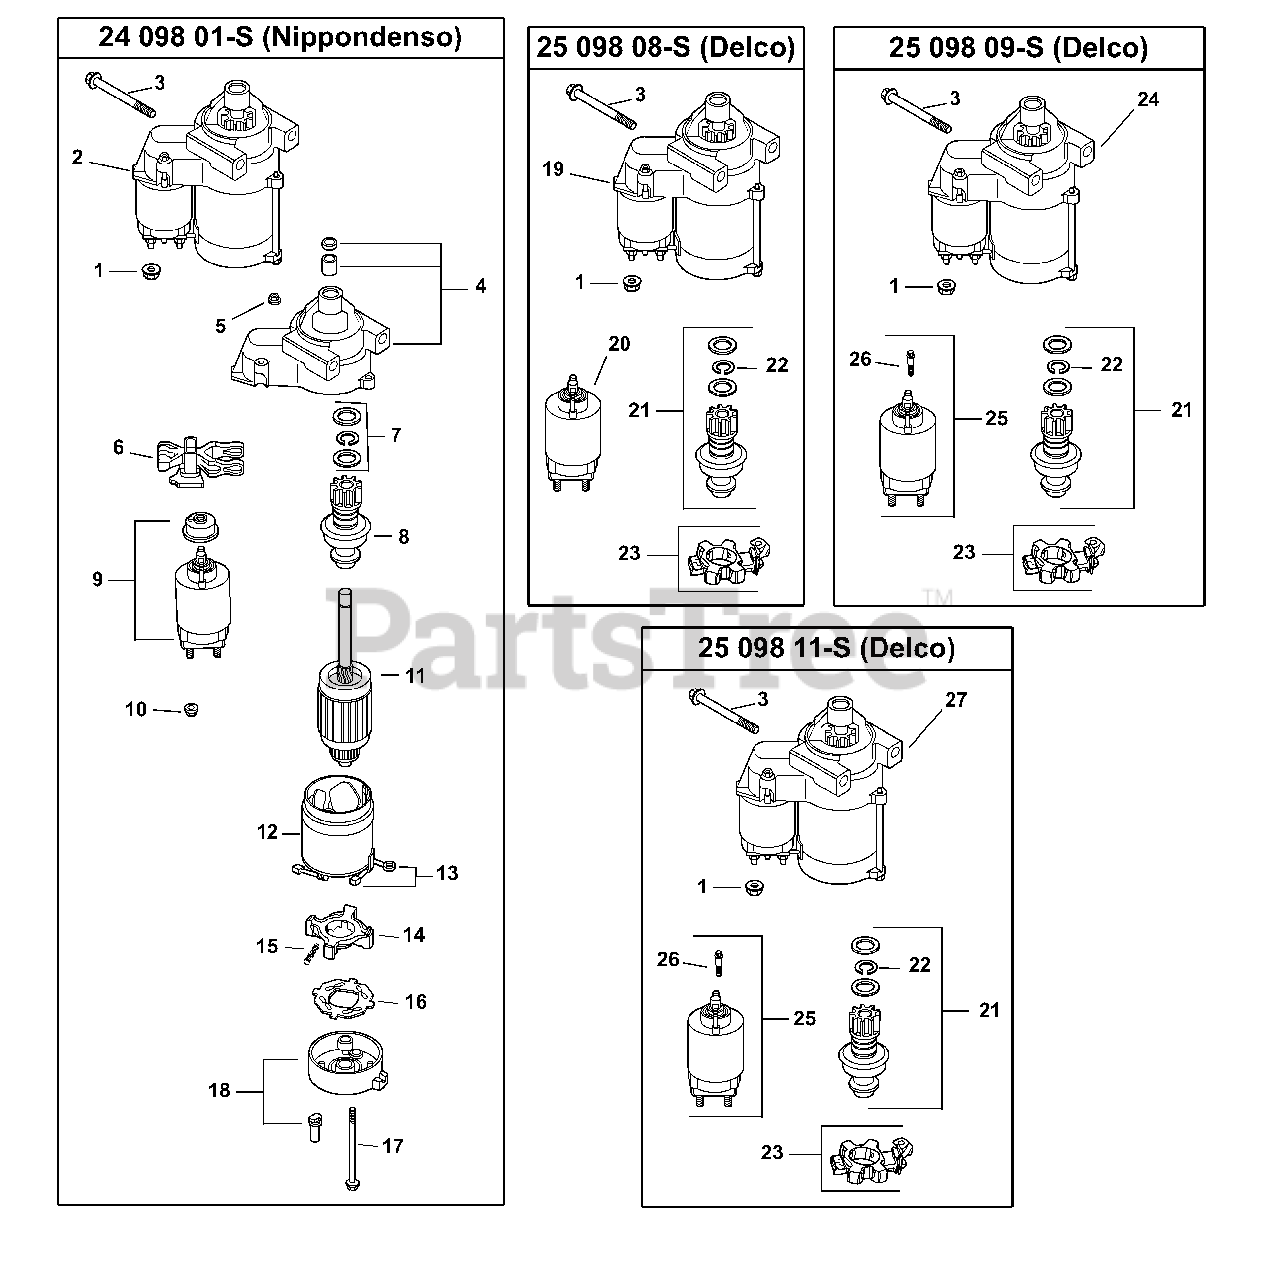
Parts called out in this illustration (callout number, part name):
1	Nut, Flg M8X1.25
2	Starter Assy, Solenoid Shift
3	Screw, Flg M8x1.25x80
4	Drive, End Cap
6	Lever, Drive
7	Kit, Starter Repair
8	Drive Pinion
12	Frame w/ Brushes
13	Brush Holder
14	Brush & Spring Kit
15	Spring, Brush
18	Commutator, End Cap
19	Starter Assy, Solenoid Shift
21	Kit, Starter Pinion (Includes 22)
22	Ring, Retaining
23	Kit, Brush Holder
24	Starter Assy, Solenoid Shift
25	Kit, Solenoid (Includes 26)
26	Screw, External Torx Head
27	Starter Assy, Solenoid Shift
